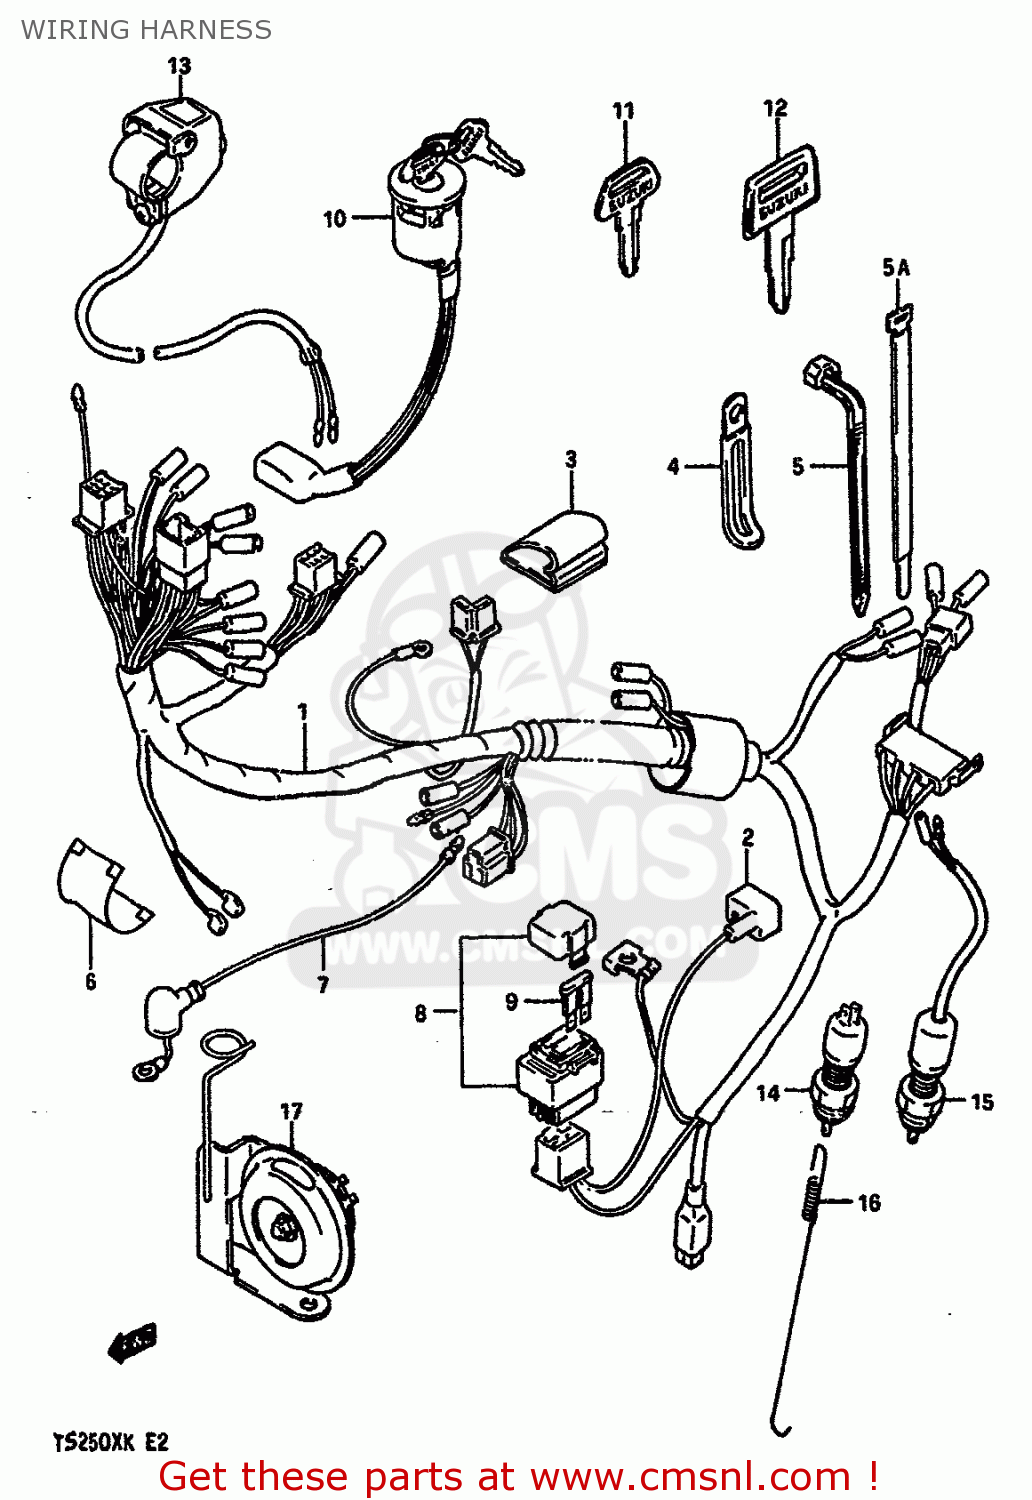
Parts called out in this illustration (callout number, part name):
1	WIRING HARNESS
2	CAP,BATTERY PLUS TERMINAL
3	CLIP
4	CLAMP
5	CLAMP(L:125)
5A	CLAMP L:110
6	COVER,WIRING HARNESS
7	WIRE,WATER TEMPERATURE
8	BOX ASSY,FUSE
9	FUSE(15A)
10	SWITCH ASSY,IGNITION
11	KEY,BLANK
12	KEY,BLANK
13	SWITCH ASSY,ENGINE STOP
14	SWITCH ASSY,STOP LAMP
15	SWITCH ASSY,STOP LAMP
16	SPRING
17	HORN ASSY
